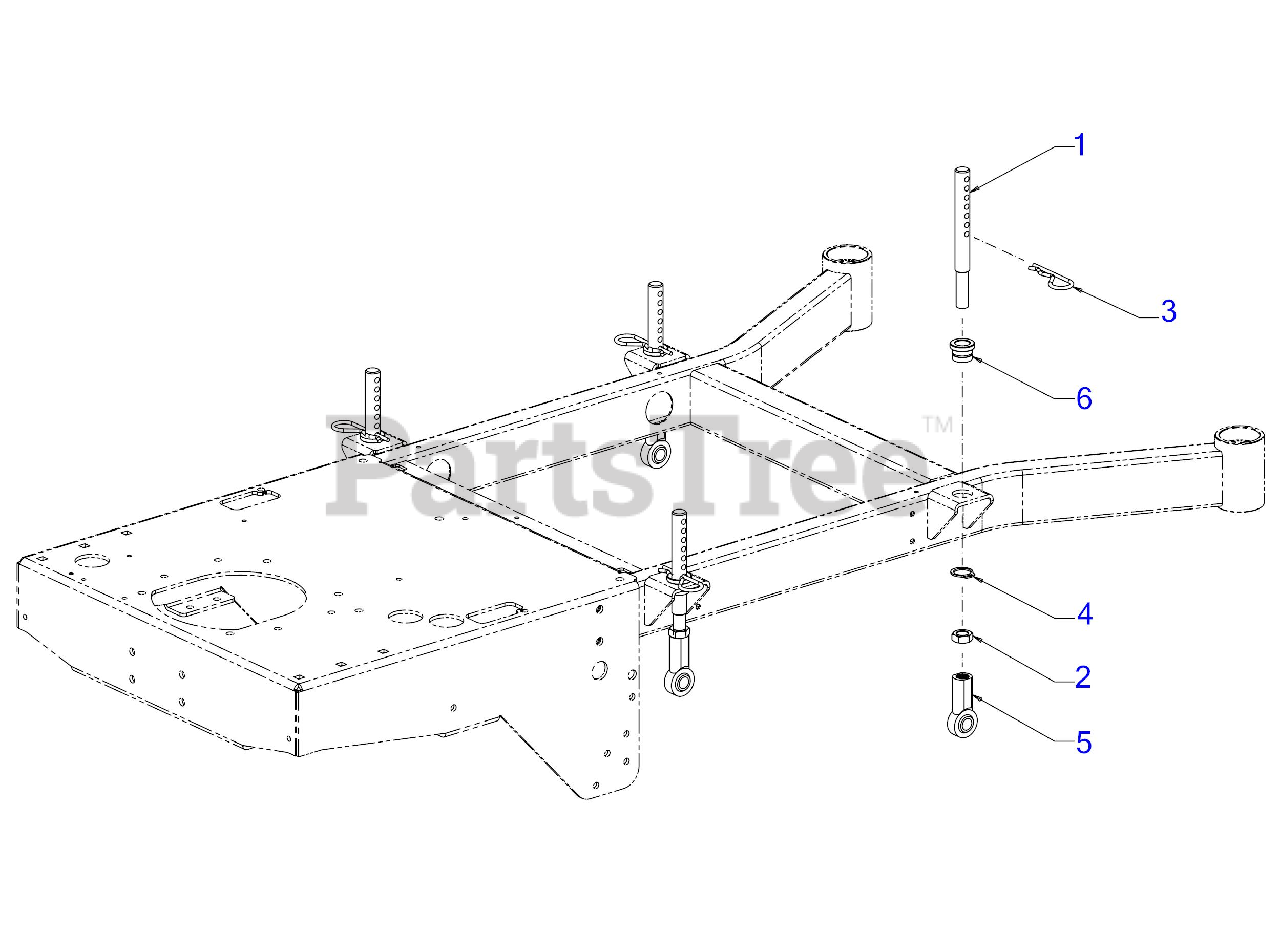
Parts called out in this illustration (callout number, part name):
1	DECK LIFT ADJUSTMENT PIN
2	HEX JAM NUT 5/8-18
3	COTTER PIN (.177 X 3.5)
4	RETAINING RING
5	BALL JOINT ROD END
6	FLANGE BUSHING (.75 ID X .875 LG)
